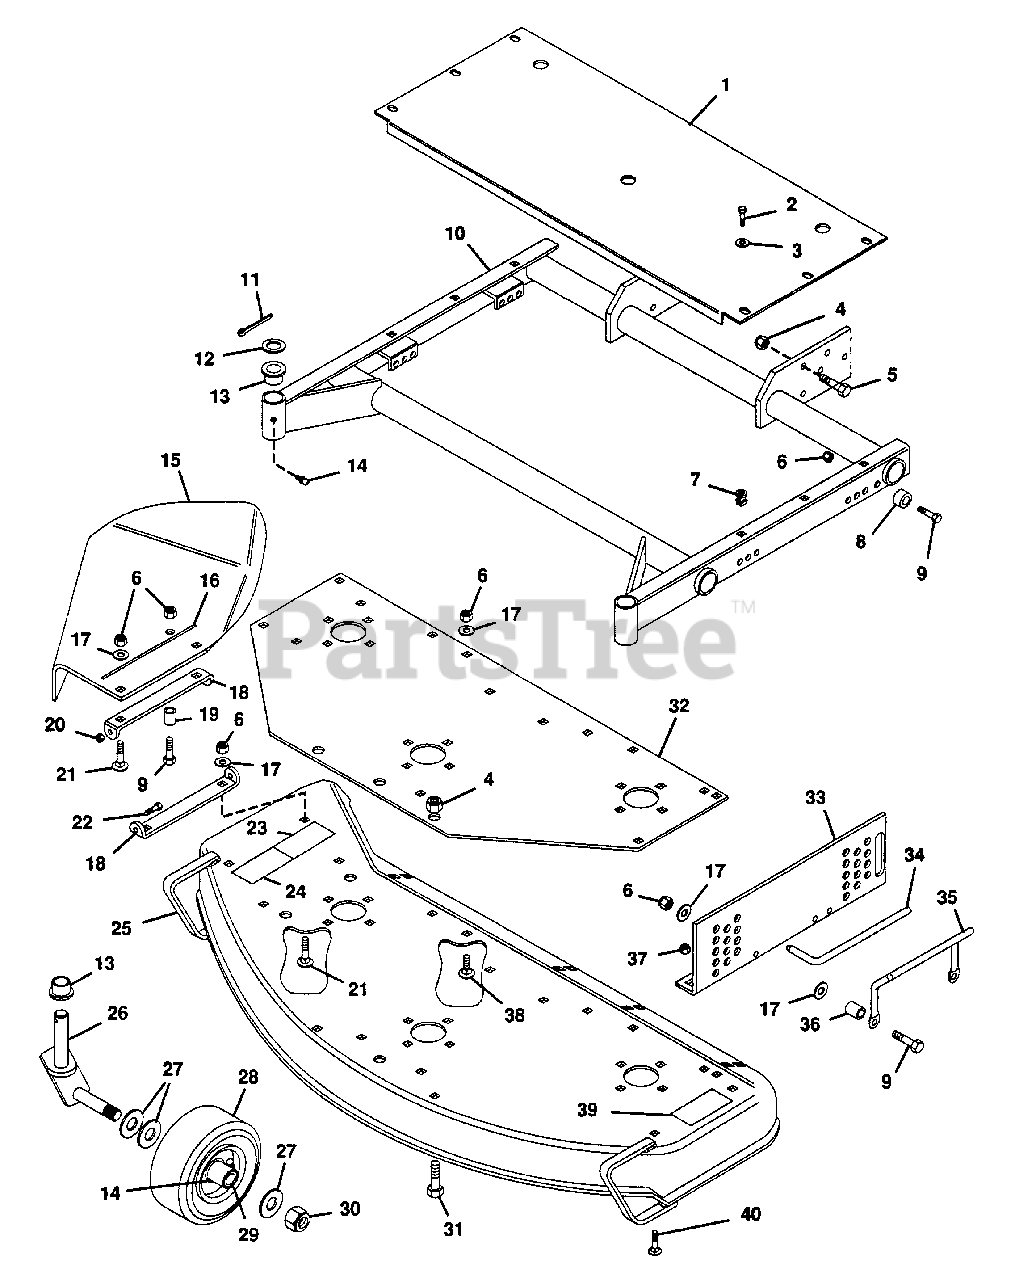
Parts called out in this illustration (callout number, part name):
1	Guard, 50" PMH Series
2	Screw, 1/4-20x.50 Self Tapping
3	Washer, Flat .281x.625x.065
4	Nut, Lock 1/2-13
5	Bolt, Hex 1/2-13x1.50
6	Nut, Lock 3/8-16
7	Grommet, Plastic
8	Bush., St. .391x.621x.676 Stl.
9	Bolt, Hex 3/8-16x1.50
10	Weldment, Mower Frame
11	Pin, Cotter .187x1.50
12	Race, Bearing Thrust
13	Bush., Flg. 1.03x1.75x.750 Ny.
14	Fitting, Lube 1/4-28
15	Shield, Safety Ext. 50" Mower
16	Decal, Width of Cut
17	Washer, Flat .406x.812x.065
18	Bracket, Chute
19	Stop, Chute
20	Nut, Lock 1/4-20
21	Bolt, 3/8-16x1.00 Rd Hd Sq Nk
22	Bolt, Hex 1/4-20x.875
23	Decal, Danger Hand
24	Decal, Warning Eye
25	Weldment, 50" Mower Deck
26	Weldment, Caster Fork
27	Washer, Flat .812x1.496x.134
28	Wheel, Gauge
29	Bearing, Gauge Wheel
30	Nut, Lock 3/4-10
31	Bolt, Hex 1/2-13x1.25
32	Plate, Support
33	Bracket, Mower Side Support L.H.
33	Bracket, Mower Side Support R.H.
34	Pin, Mower Locking
35	Handle
36	Bushing
37	Nut, Lock 5/16-18
38	Bolt, Carriage 3/8-16x.75
39	Decal, Danger Foot
40	Bolt, Carriage 5/16-18x1.00
